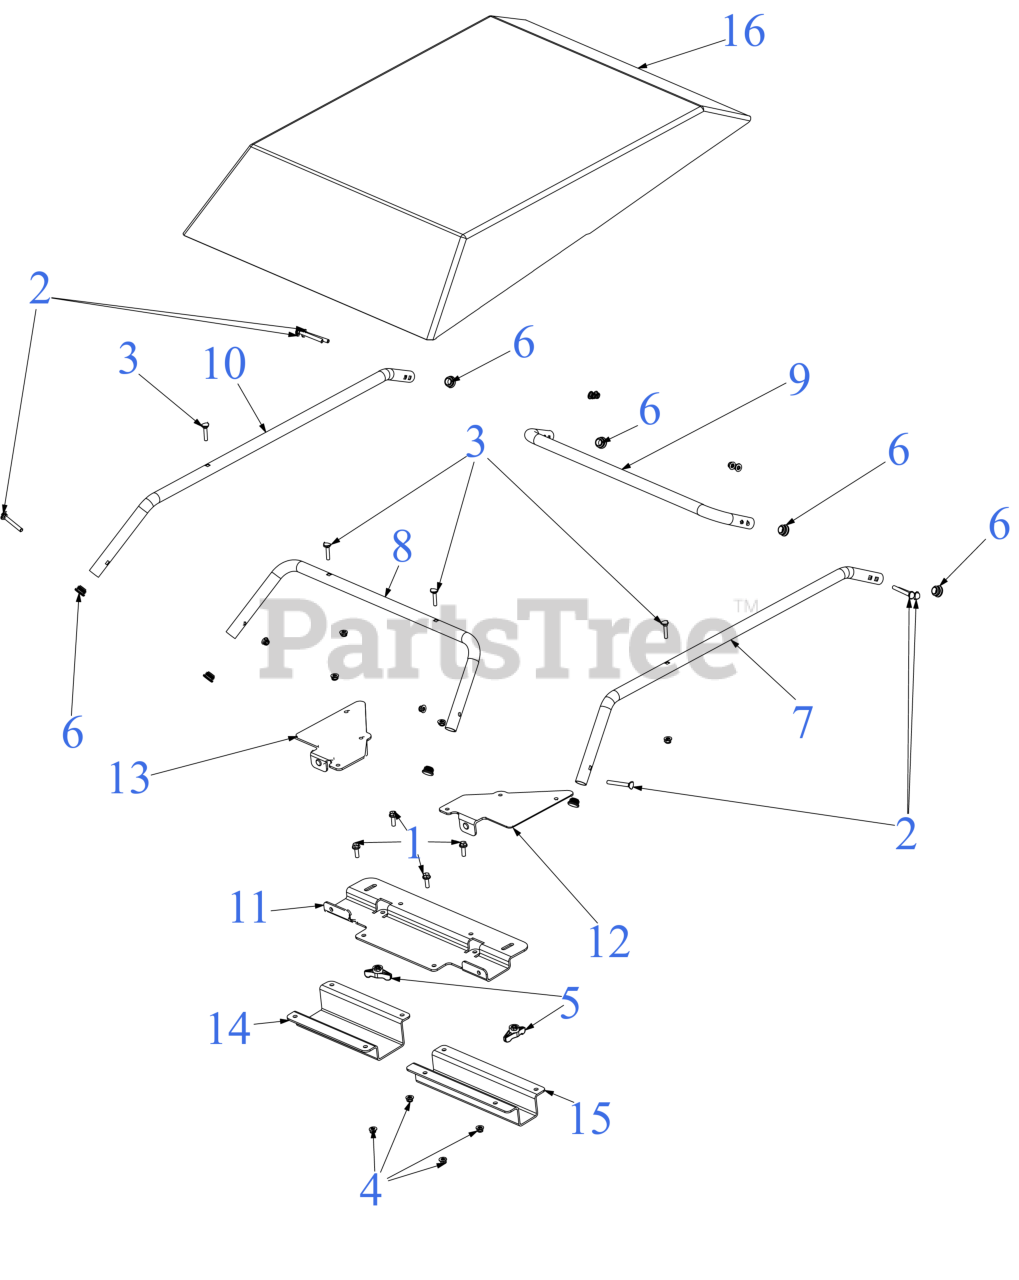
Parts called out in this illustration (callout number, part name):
1	SCREW 5/16-18 x 1 GR5
2	BOLT 5/16-18 x 2.5
3	CARRIAGE BOLT 5/16-18 x 1.5
4	FLANGE LOCK NUT 5/16-18
5	WING KNOB 5/16-18
7	Not Serviceable/ Order Complete Assembly
8	Not Serviceable/ Order Complete Assembly
9	Not Serviceable/ Order Complete Assembly
10	Not Serviceable/ Order Complete Assembly
11	Not Serviceable/ Order Complete Assembly
12	Not Serviceable/ Order Complete Assembly
13	Not Serviceable/ Order Complete Assembly
14	Not Serviceable/ Order Complete Assembly
15	Not Serviceable/ Order Complete Assembly
16	Not Serviceable/ Order Complete Assembly
